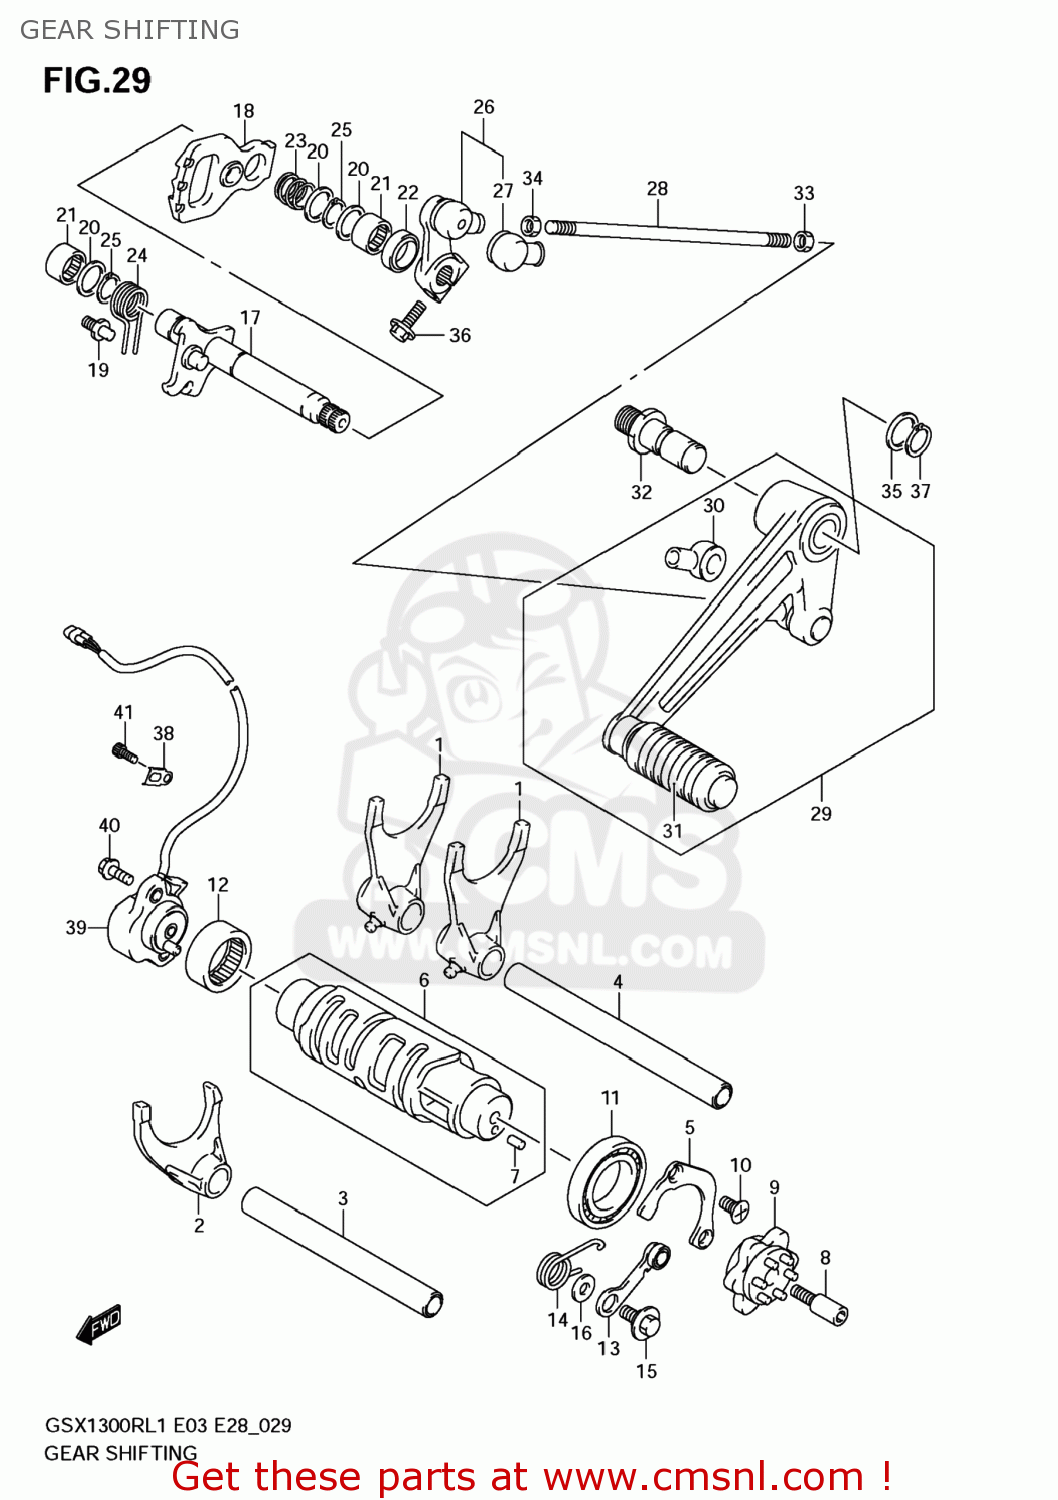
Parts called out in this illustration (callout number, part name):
1	FORK,GEAR SHIFT NO.1
2	FORK,GEAR SHIFT NO.3
3	SHAFT,SHIFT FORK NO.2(L:132)
4	SHAFT,GEAR SHIFT FORK(L:152)
5	RETAINER,SHIFT CAM BEARING
6	CAM,GEAR SHIFT
7	PIN
8	BOLT,GEAR SHIFT CAM PLATE
9	PLATE,GEAR SHIFT CAM
10	SCREW(6X12)
11	BEARING(25X47X8)
12	BEARING(25X32X12)
13	STOPPER,SHIFT CAM
14	SPRING,STOPPER ARM
15	BOLT(6X14.3)
16	WASHER
17	SHAFT,GEAR SHIFT
18	PLATE,GEAR SHIFT CAM DRIVE
19	STOPPER,GEAR SHIFT ARM
20	SHIM(14X22X1)
21	BEARING(14X20X12)
22	SEAL,OIL(14X22X7.3)
23	SPRING
24	SPRING
25	CIRCLIP
26	ARM,GEAR SHIFT LINK
27	COVER,DUST
28	ROD,GEAR SHAFT LINK
29	GEAR SHIFTING LEVER
30	COVER,DUST
31	RUBBER,GEAR SHIFT PEDAL
32	SHAFT,GEAR SHIFT LEVER
33	NUT
34	NUT
35	WASHER(12.5X20X1)
36	BOLT
37	CIRCLIP
38	CLAMP,GENERATOR LEAD WIRE
39	SENSOR. VERSNEL
40	BOLT
41	BOLT
